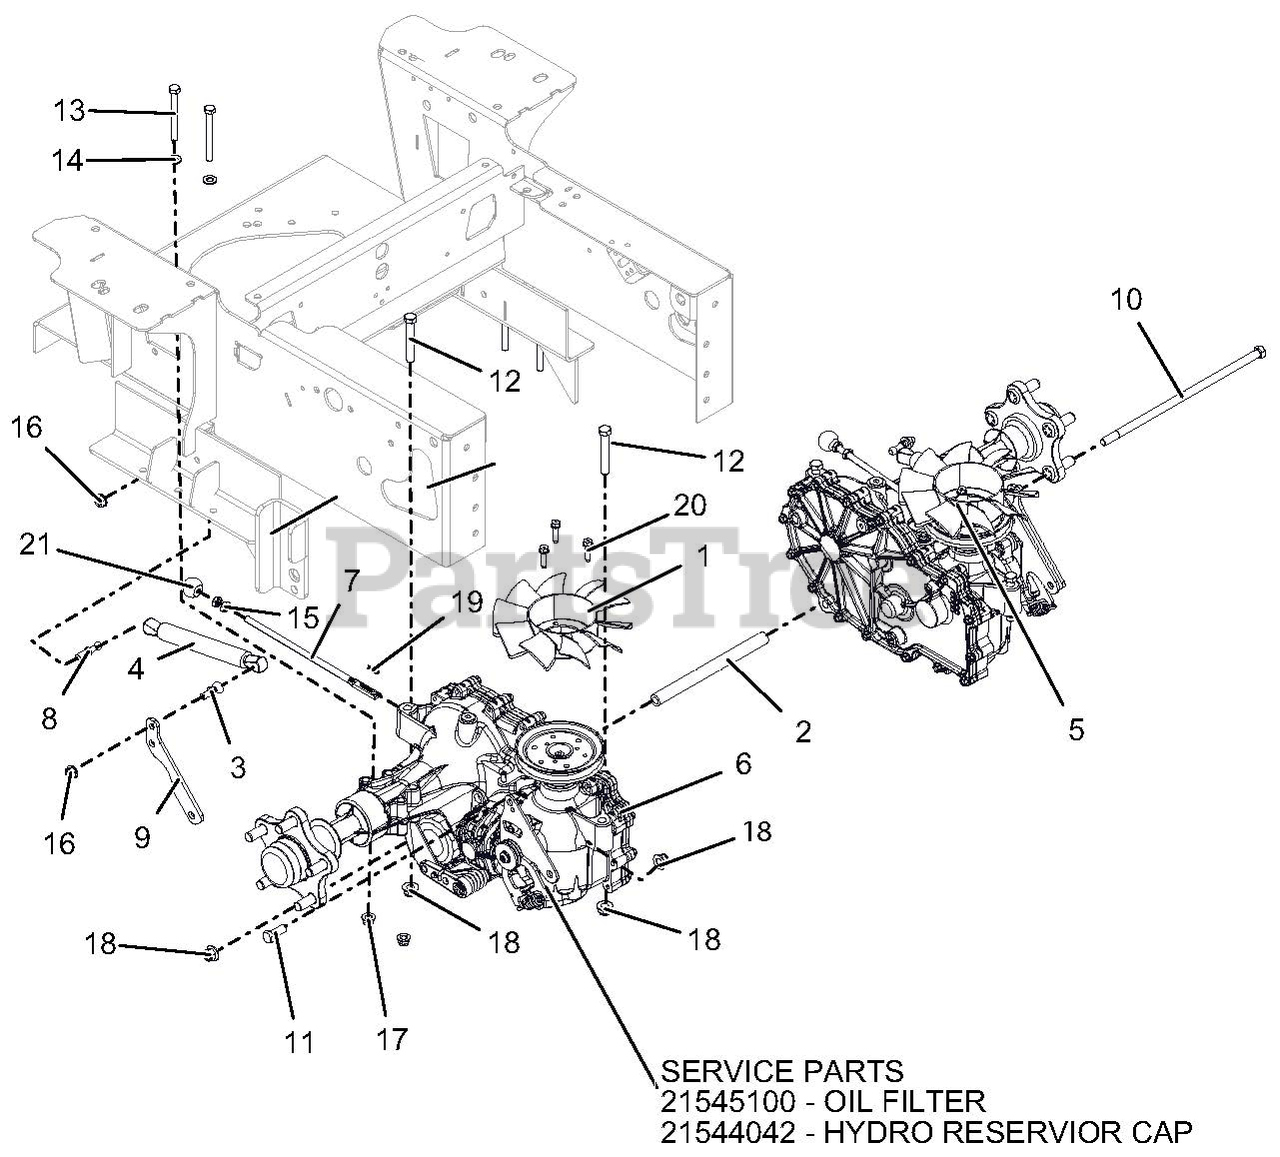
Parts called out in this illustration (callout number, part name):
1	FAN, 2800 SERIES COOLING
2	SPACER, .406 ID X .630 OD X 7.724
3	STUD-BALL
4	DAMPER,
5	TRANSAXLE, ZT3400 - LH
6	TRANSAXLE, ZT3400 - RH
6	OIL FILTER
6	HYDRO RESERVOIR CAP
7	LEVER, PT100 DUMP VALVE
8	STUD, BALL THREADED
9	TRANSMISSION DAMPER MTG PLATE - BLK
10	BLT, HEX .38-16X11.00 GR5 YWZC
11	BLT-HEX .38-16X1.00 GR5 YWZC
12	BLT-HEX .38-16X2.50 GR5 YWZC
13	BLT-HEX .31-18X3.00 GR5 YWZC
14	WSHR-FL-STL.344X.688X.065YWZC
15	NUT, JAM .312-18 YWZC
16	NUT, LK-TOP-FLG .312-18 YWZC
17	NUT-LK-NYL-FLG .31-18 YWZC
18	NUT-LK-NYL-FLG .38-16 YWZC
19	PIN-HAIR INT .06X.18X.77
20	SCR-TAP .25-20X1.00 HWH TR YZ
21	KNOB, BALL -BLACK .312-18
